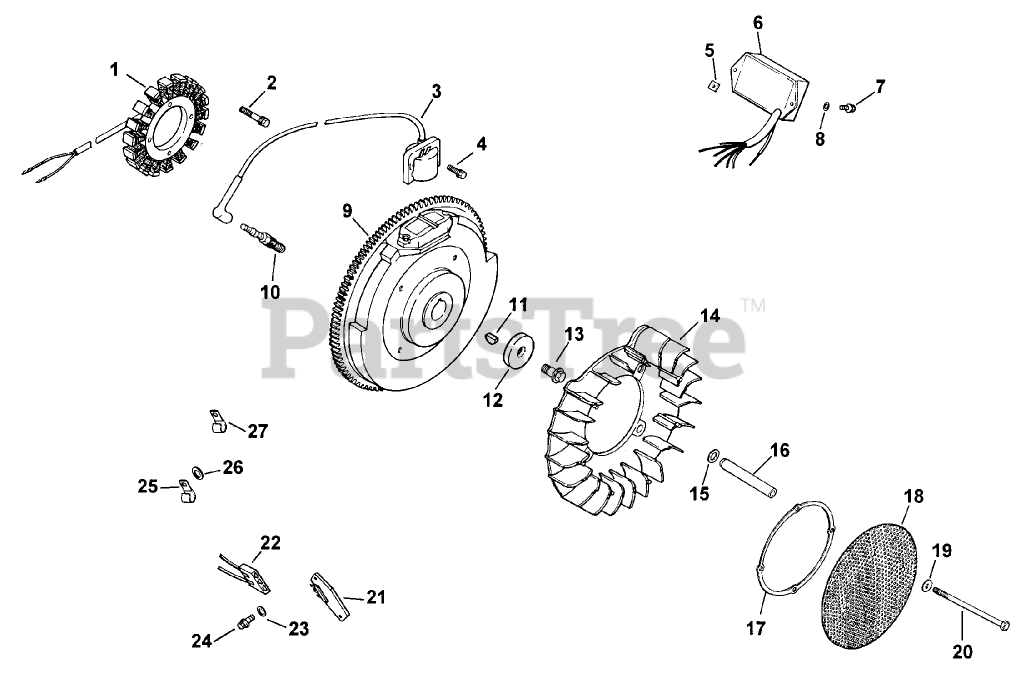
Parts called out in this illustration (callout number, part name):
1	Kit, 15 amp stator (Incl. 28 )
2	SCREW-THREAD FORMING (M5X0.8X25)
3	Module-Ignition
4	Screw-Socket, Hex (M5x0.8x25)
5	NUT-PLASTIC
6	Module-Advance, Speed
7	SCREW-PPH (11-16X1/2)
8	Washer-Lock, Internal Tooth (1/4)
9	Flywheel
10	SPARK PLUG
11	KEY (3/16 X 5/8)
12	WASHER-FLAT (13/32)
13	SCREW-FLANGE (M10X1.5X45)
14	Fan
15	Washer-Spring (10MM)
16	Spacer
17	Ring-Support
18	Screen-Grass
19	WASHER-FLAT (1/4)
20	Screw-HH (M6x1.0x100)
21	Rectifier-Regulator, 15 amp
22	Connector (3 contact)
23	WASHER-FLAT (.188)
24	SCREW-PHL HD (11-16X.88)
25	CLIP-CABLE
26	WASHER-FLAT (1/4)
27	Clip-Cable
28	Bracket-Wire, Stator
29	Kit, chopper screen (incl. 15-19)
